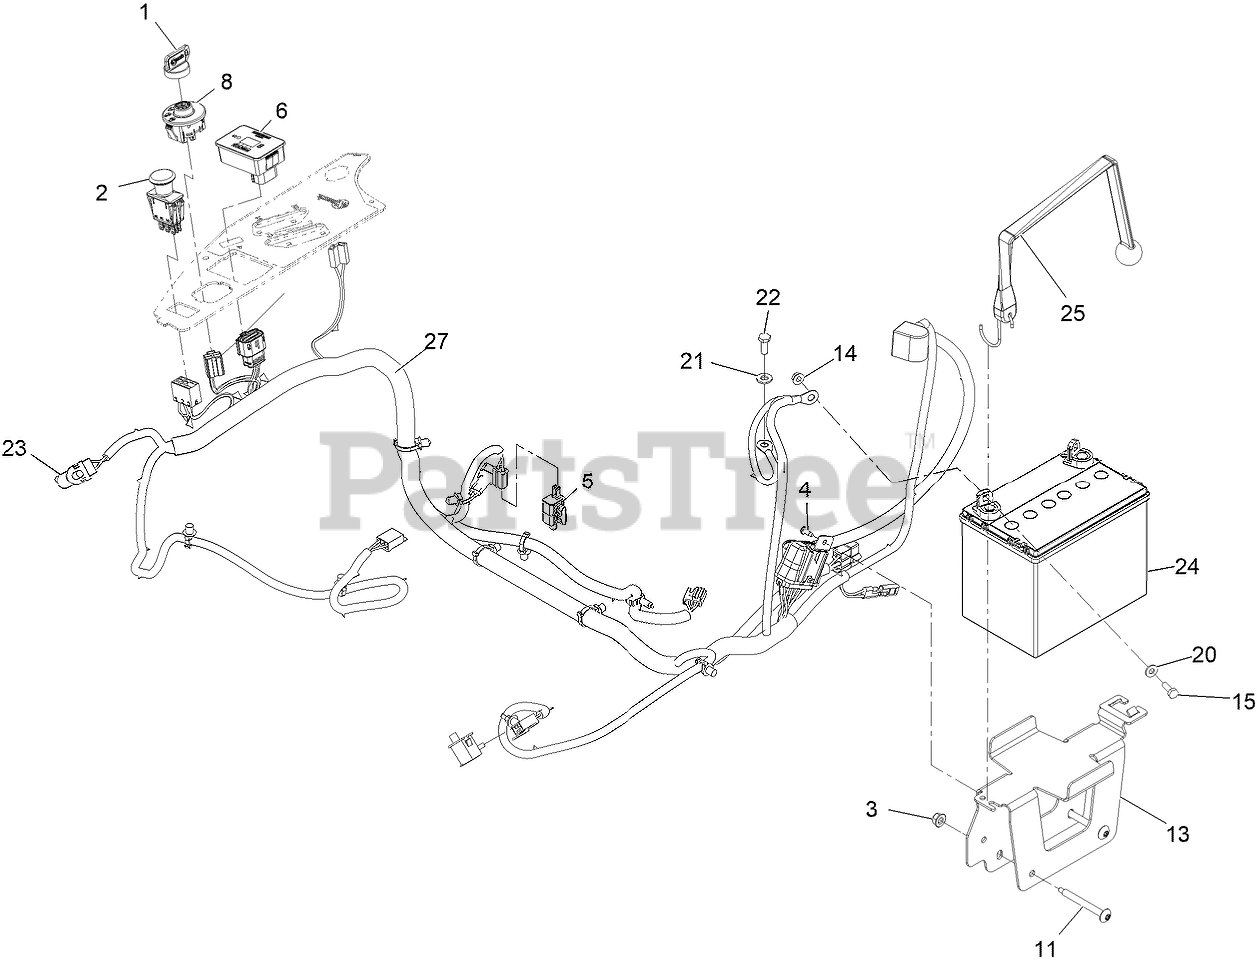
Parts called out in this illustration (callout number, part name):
1	KEYS-IGNITION (SPARE PAIR
1	KEY-IGNITION
2	SWITCH-PTO
3	NUT-HF, NI
4	SCREW-FORMING, THREAD
6	MODULE ASM
8	SWITCH-IGNITION
11	SCREW-TORX
13	TRAY-BATTERY
15	SCREW-HH
20	WASHER-FLAT
21	WASHER-PLAIN
22	SCREW-HH
23	SWITCH-BAIL
24	Battery
25	STRAP-BUNGEE
27	HARNESS-WIRE
